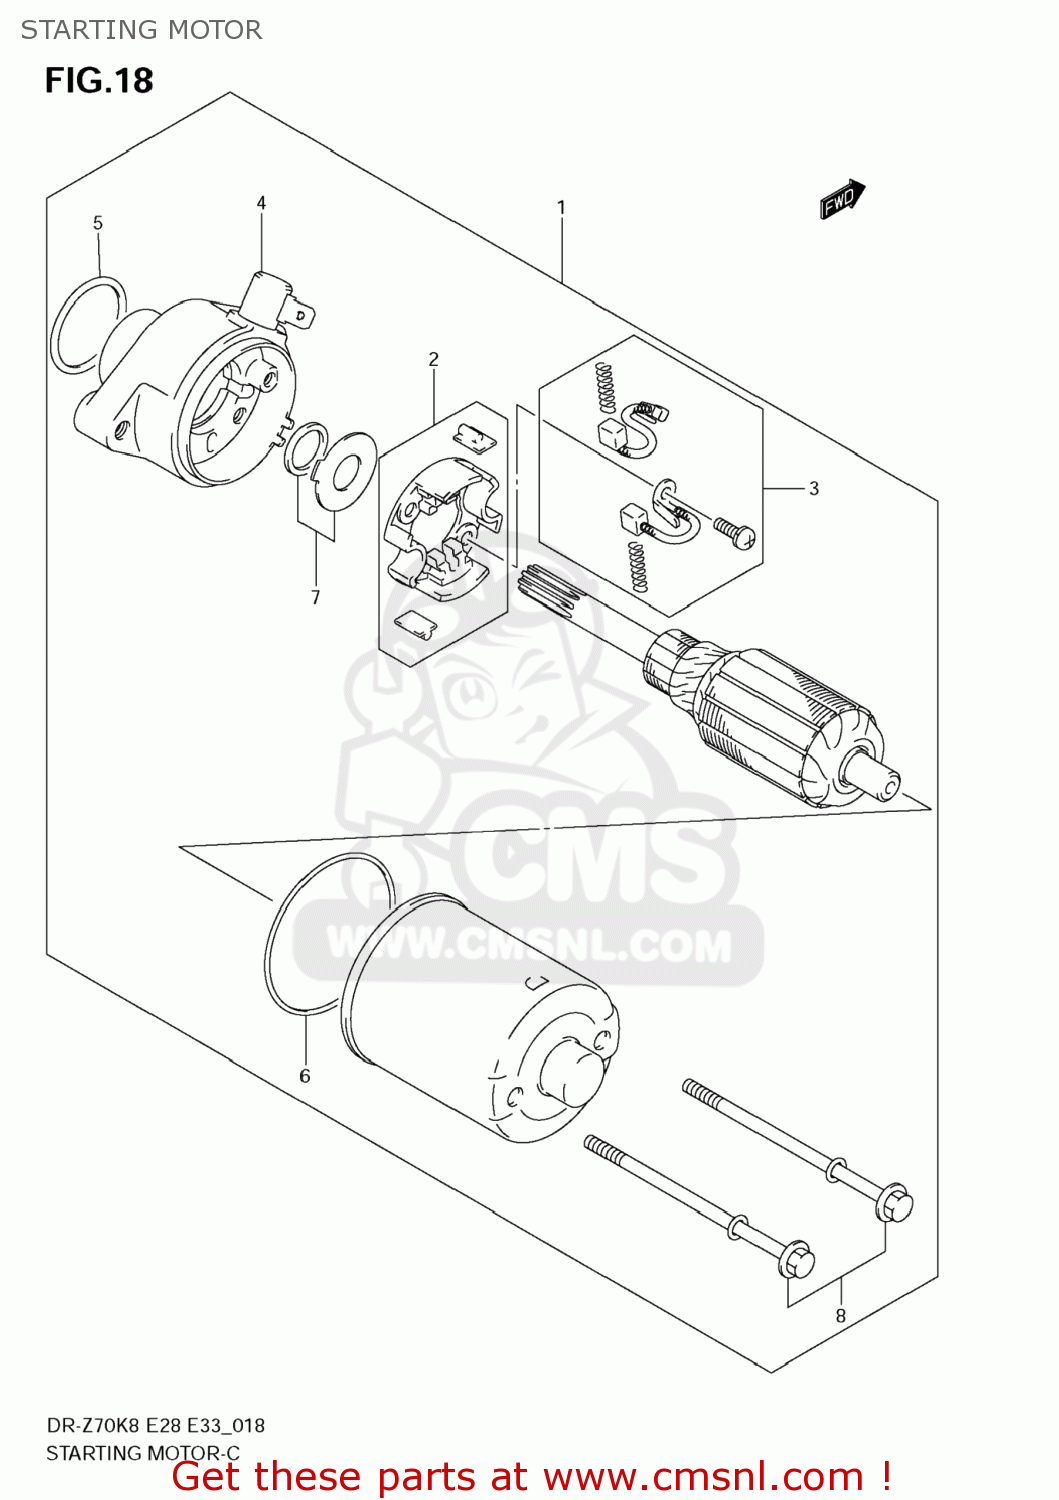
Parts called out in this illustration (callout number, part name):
1	MOTOR ASSY,STARTING
2	HOLDER SET,BRUSH
3	BRUSH SET
4	HOUSING ASSY
5	O RING(D:2.4,ID:24.7)
6	O RING
7	SHIM SET,STARTING MOTOR
8	BOLT,STARTER MOTOR
